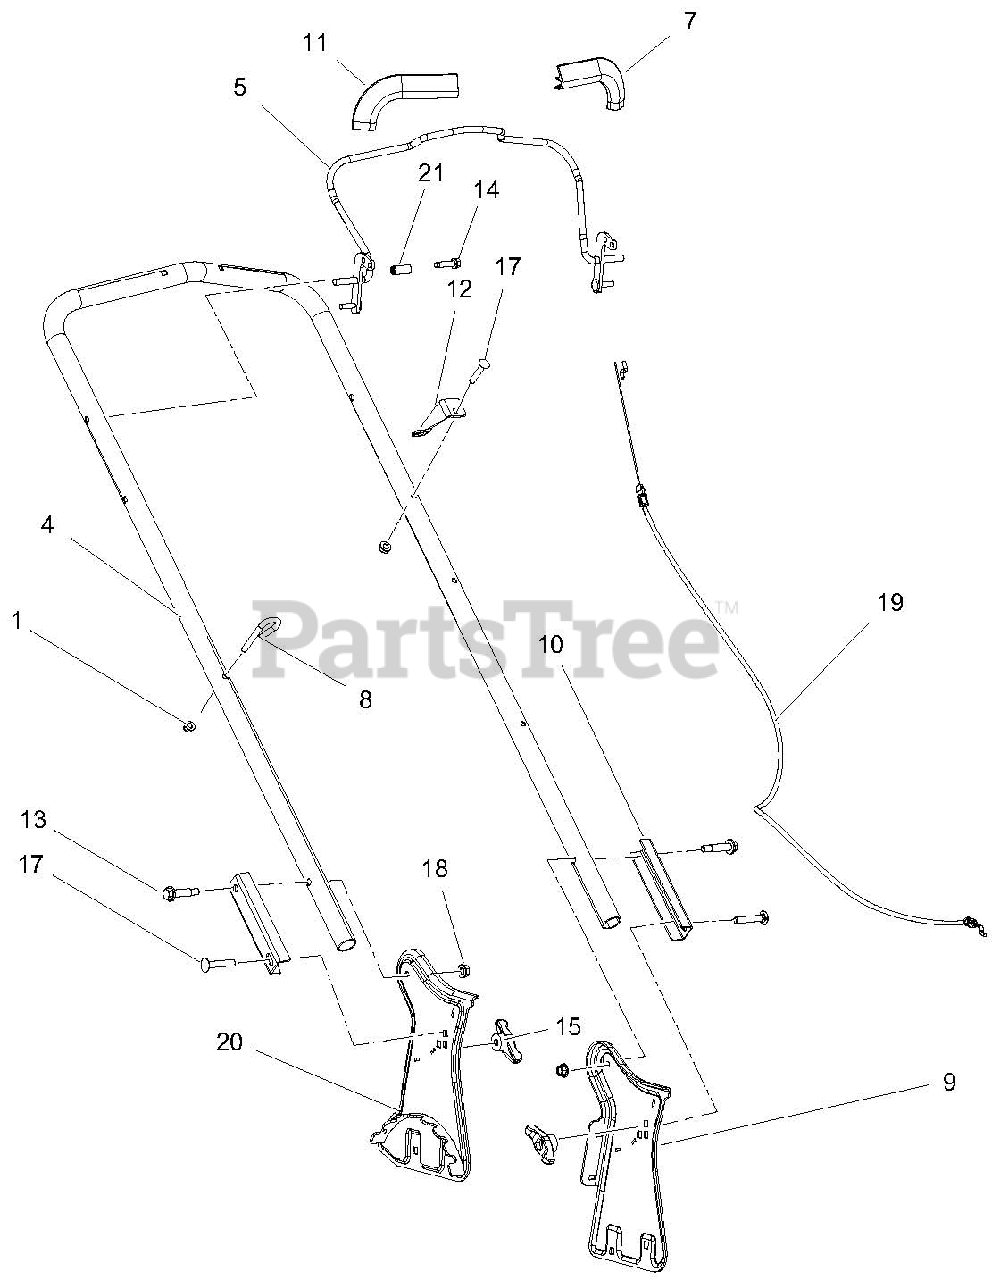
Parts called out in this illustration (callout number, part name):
1	@NUT-LK-TOP-FLG .25-20 YWZC
4	HANDLEBAR, LM
5	WLDMT, OPC BAIL
7	GUARD, FINGER - LH
8	HOLDER, RECOIL CORD
9	SUPPORT, LH HANDLEBAR
10	BRKT, HANDLEBAR FIXED ADJUST
11	HAND GRIP W/ DECAL
12	BRKT, CABLE ANCHOR - LM PUSH
13	BLT-SHLDR, .50X1.15X.312-18GR5
14	@SCR-TAP .25-20X1.00 HWH TR YZ
15	KNOB,WING .31-18 UNC NYL/TALC
17	@BLT-RDHDSQNK .25-20X1.50 G5YZ
18	@NUT-LK-TOP-FLG .31-18 YWZC
19	CABLE, OPC
20	SUPPORT, RH HANDLBAR
21	CAP, VINYL, .25 ID
